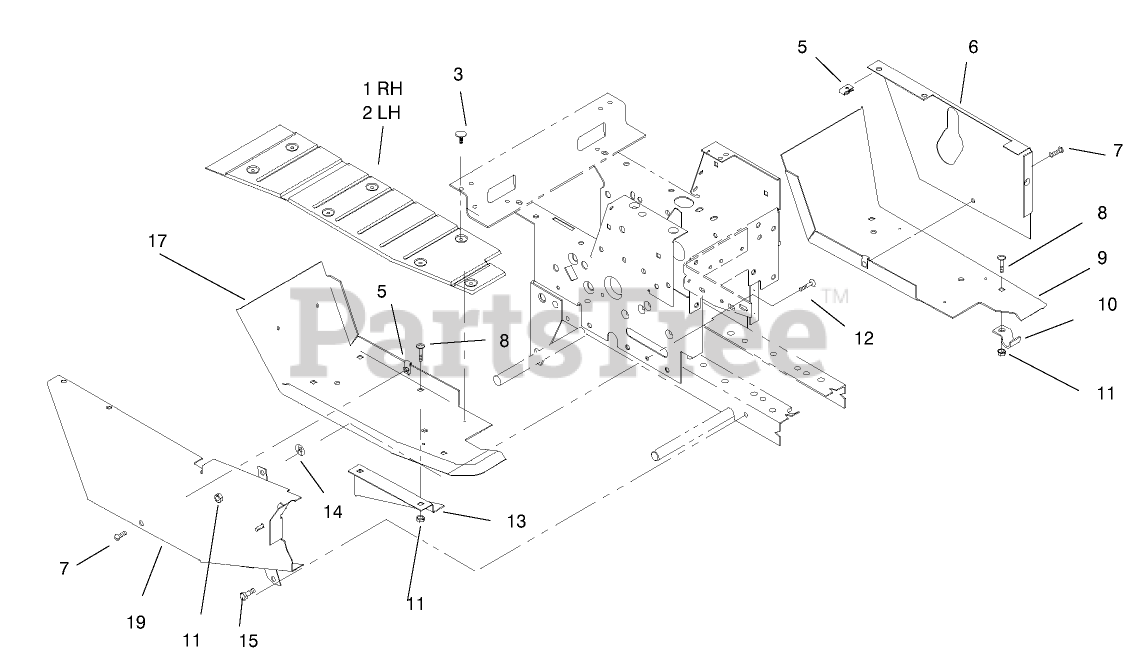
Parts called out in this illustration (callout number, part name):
1	PAD-FOOT RH
2	PAD-FOOT LH
3	FASTENER-PANEL
6	COVER-LH
7	SCREW-PPH
8	BOLT-CARR
9	FOOTREST-LH
10	BRACKET
11	NUT-LOCK, NI
12	BOLT-CARR
13	GUIDE-LOWER BELT
15	SCREW-HWHTF
17	FOOTREST-RH
